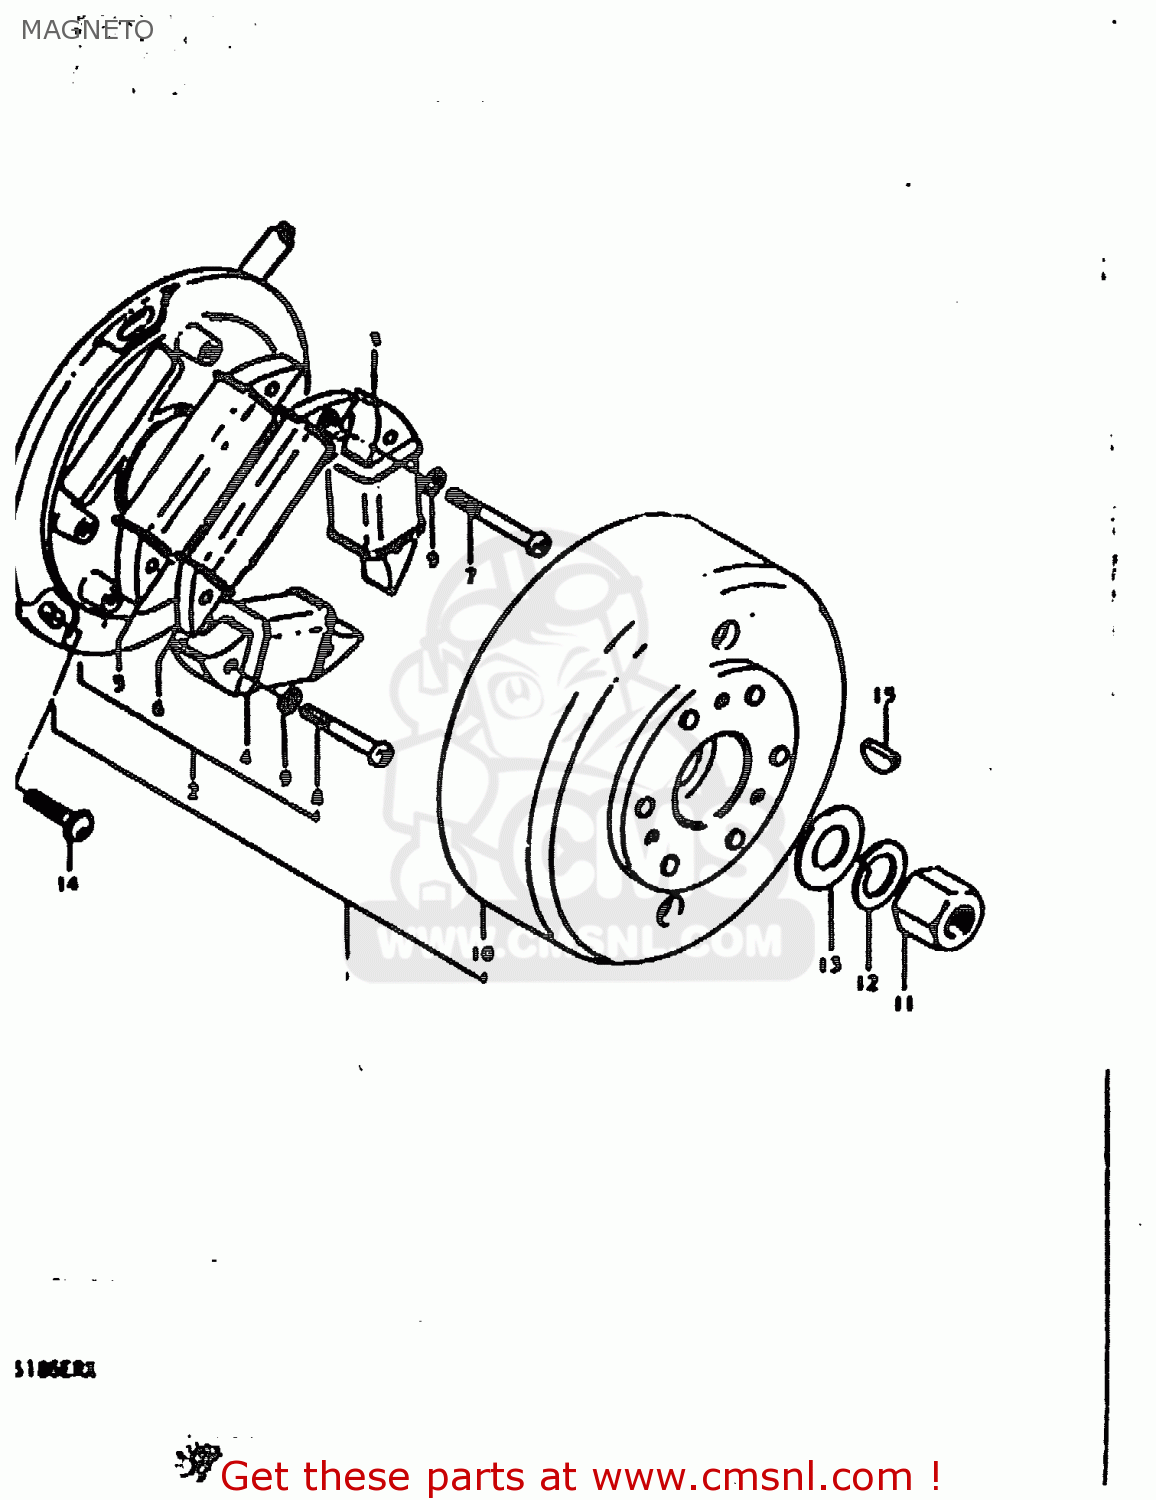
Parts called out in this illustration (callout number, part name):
1	MAGNETO ASSEMBLY
2	STATOR ASSEMBLY
3	COIL,CHARGE
4	COIL,LIGHTING
5	COIL,PRIMARY
6	COIL,PULSER
7	SCREW
8	SCREW 5X20
9	LOCK WASHER
10	ROTOR,FLYWHEEL
11	NUT
12	LOCK WASHER
13	WASHER(14X27X3)
14	SCREW(5X14)
15	KEY 4MM
